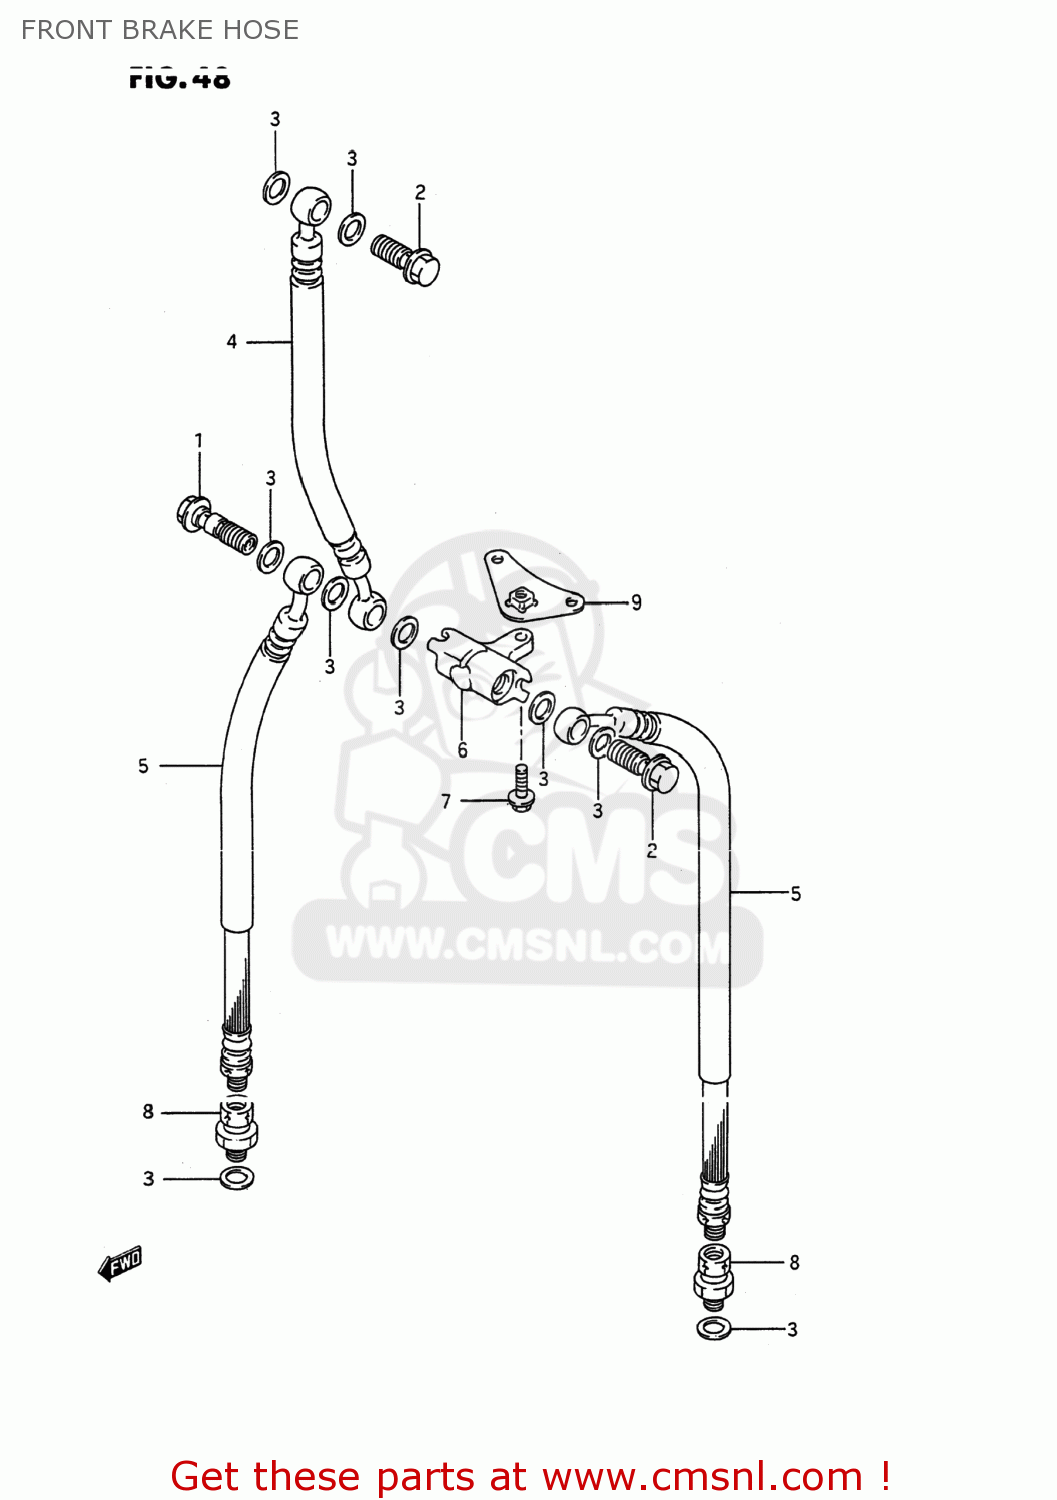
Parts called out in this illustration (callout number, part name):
1	BOLT UNION
2	BOLT UNION
3	WASHER(10X15X1.5)
4	HOSE,FRONT BRAKE
5	HOSE,FRONT BRAKE
6	JOINT,BRAKE HOSE
7	BOLT
8	ADAPTER,BRAKE HOSE
9	PLATE,FRONT BRAKE JOINT
